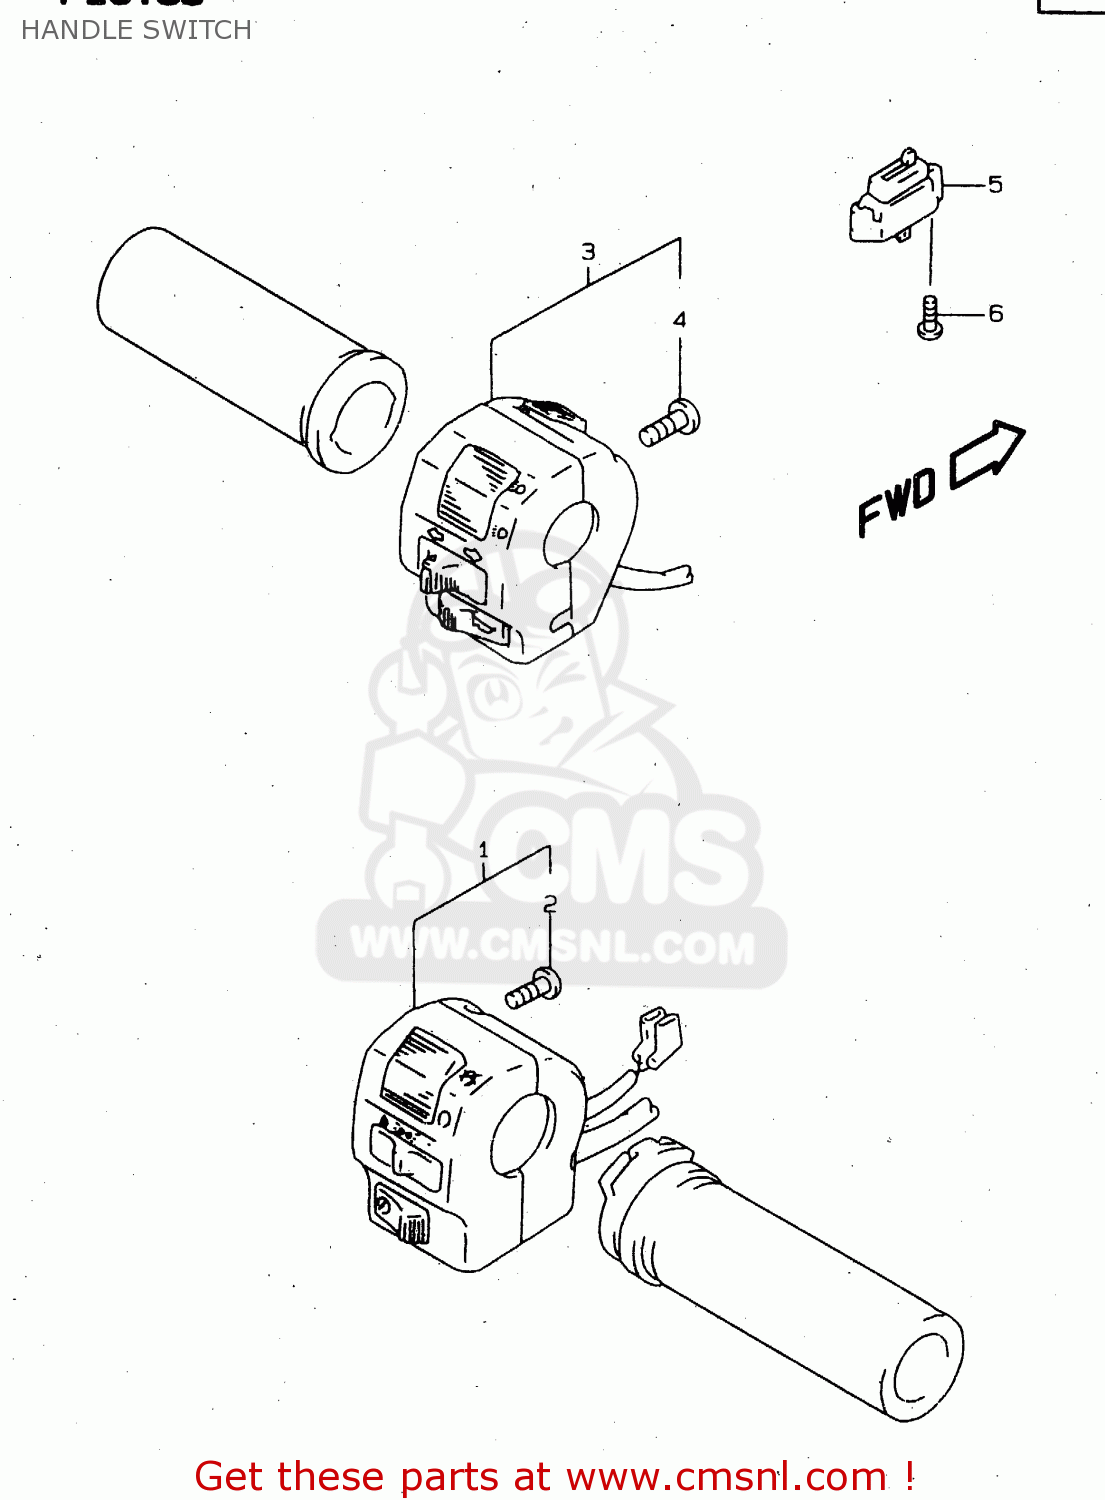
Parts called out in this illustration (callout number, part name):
1	SWITCH ASSY,HANDLE,R
2	SCREW
3	SWITCH ASSY,HANDLE,L
4	SCREW
5	SWITCH ASSY,CLUTCH
6	SCREW
